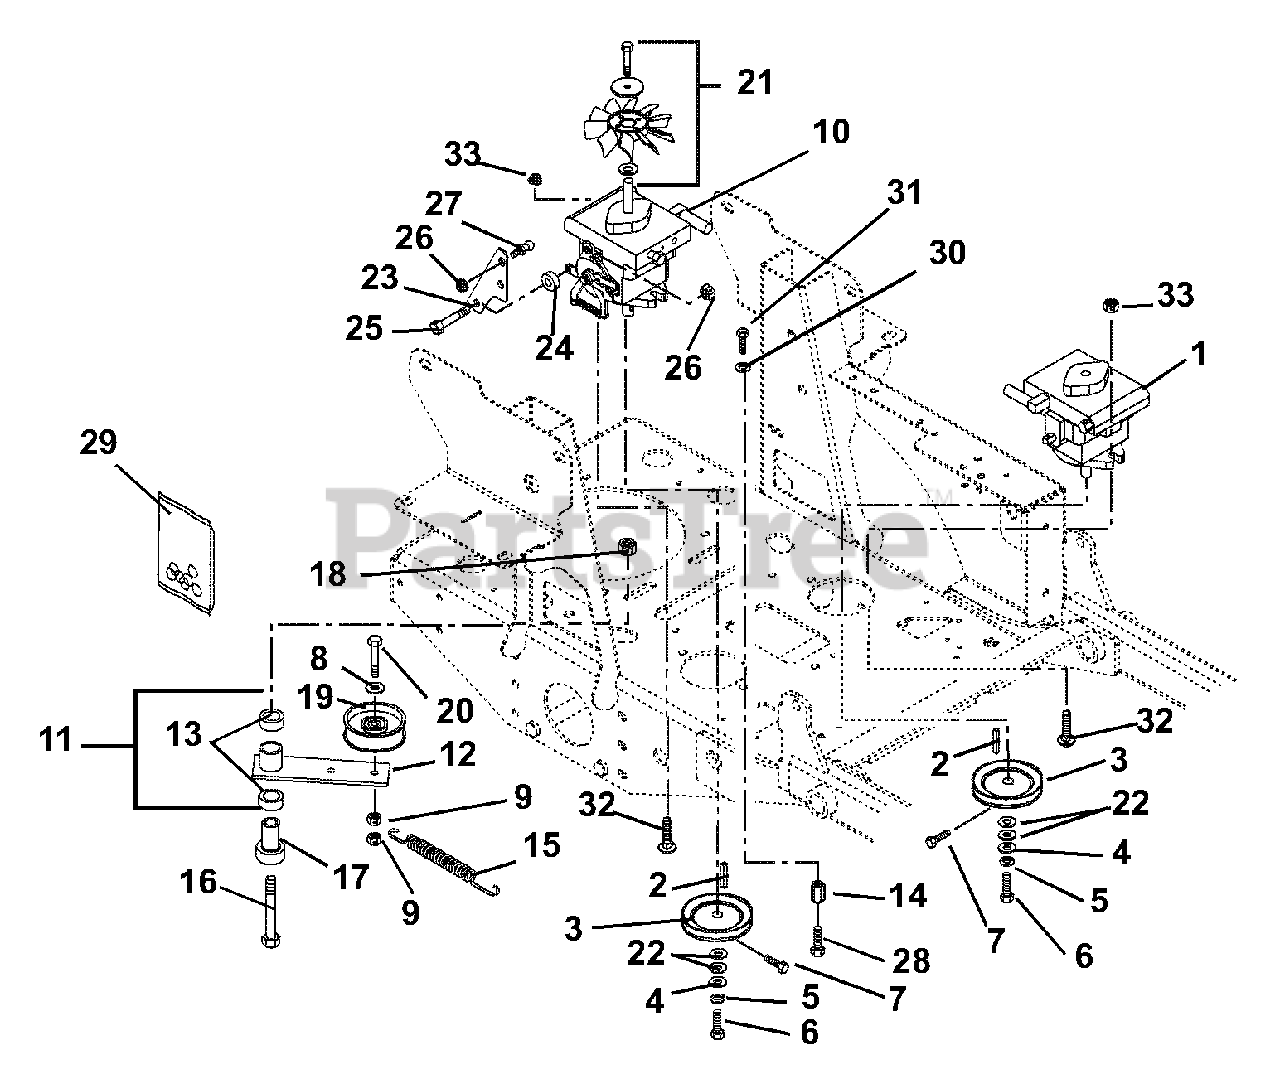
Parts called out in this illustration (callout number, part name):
1	PUMP, HYD BDP-10A (LH)
2	KEY-STR 5MMX25MMX5MM
3	SHEAVE, PUMP .592 X 4.345
4	WSHR-FL-STL .281X1.000X.063
5	@WSHR-LK .25X.062 REG YWZC
6	BLT-HEX M6 X 1.0X12 YWZC
7	BLT-HEX .25-20X.50 GR5 EPOXY
8	WSHR-FL-STL .390X.75X.125 YWZC
9	@NUT-LK-TOP-FLG .38-16 YWZC
10	PUMP, BDP-10A-441 (THRU SHAFT)
11	ASSEMBLY,IDLER ARM GRD.DRIVE
12	WMT, IDLER ARM GROUND DRIVE
13	BRG, 1.00 X 1.12 X .75
14	NUT COUPLING .375-16X1.75
15	SPRING, EXTENSION
16	@BLT-HEX .50-13X3.50 GR5 YWZC
17	BEARING, PEDESTAL
18	@NUT-LK-TOP-FLG .50-13 YWZC
19	IDLER, FLAT 4.00X1.06
20	@BLT-HEX .38-16X2.25 GR5 YWZC
21	FAN, COOLING
22	@WSHR-FL-STL.656X1.31X.095 YWZ
23	BRACKET, RTN/DAMPER
24	SPACER .344X1.000X.375
25	@BLT-HEX .31-18X1.25 GR5 YWZC
26	@NUT-LK-TOP-FLG .31-18 YWZC
27	STUD- BALL
28	@BLT-HEX .38-16X1.50 GR5 YWZC
29	KIT, PUMP SEAL
30	@WSHR-LK .38X.094 REG YWZC
31	@BLT-HEX .38-16X.75 GR5 YWZC
32	@BLT-RDHDSQNK .44-14X1.50 G5YZ
33	NUT-LK-NYL-FLG .44-14 YWZC
